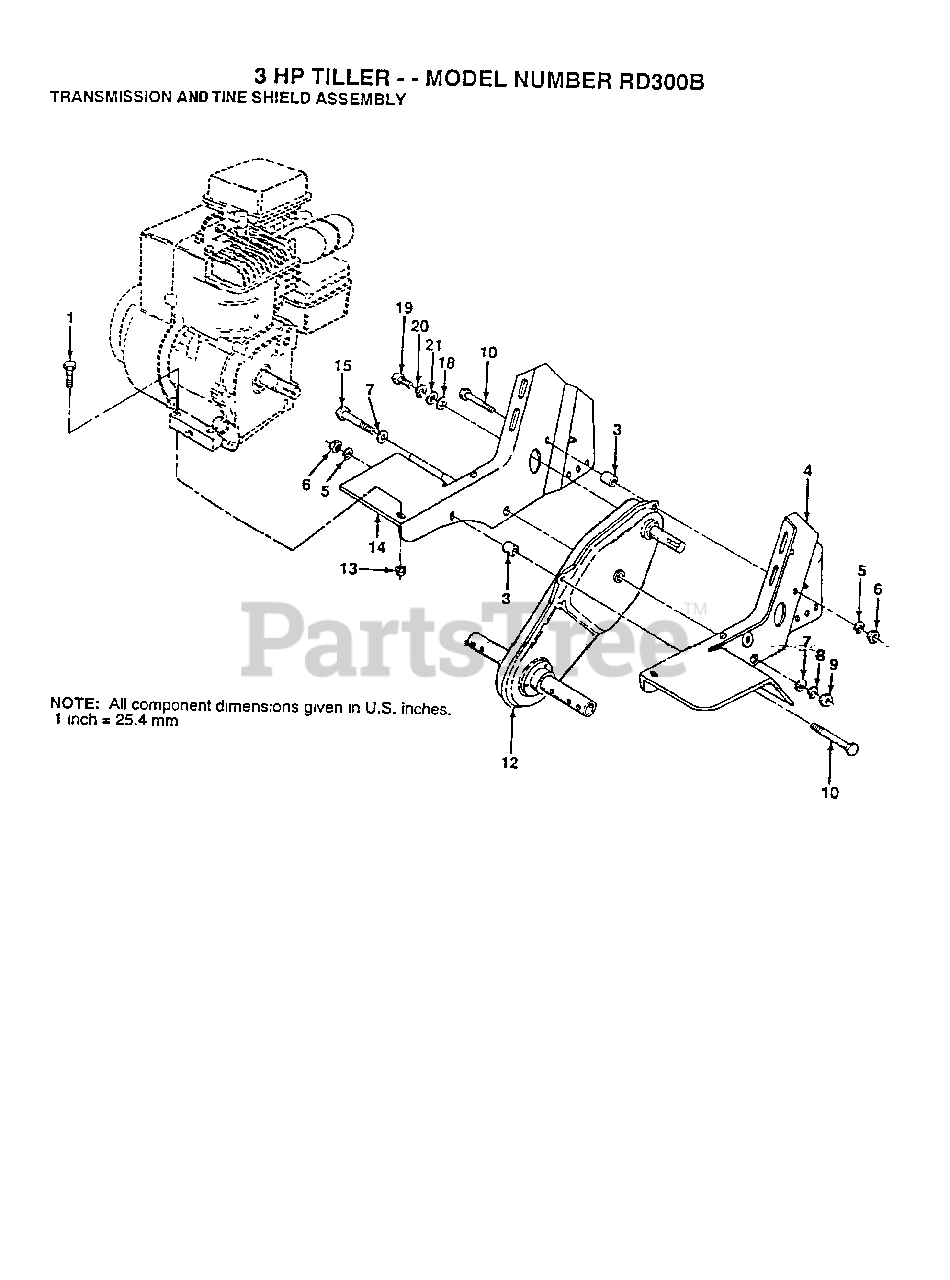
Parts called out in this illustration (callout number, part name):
1	BOLT.HEX.5/16-1.5
3	SPLIT SPACER RT
5	LOCKWASHER
6	NUT.HEX.5/16-18
7	WASHER
8	LOCKWASHER
9	GRIPCO NUT
14	"BRKT,ENG RH"
15	BOLT.3/8-24X3.75
18	WASHER
19	BOLT
20	LOCKWASHER
21	WASHER
